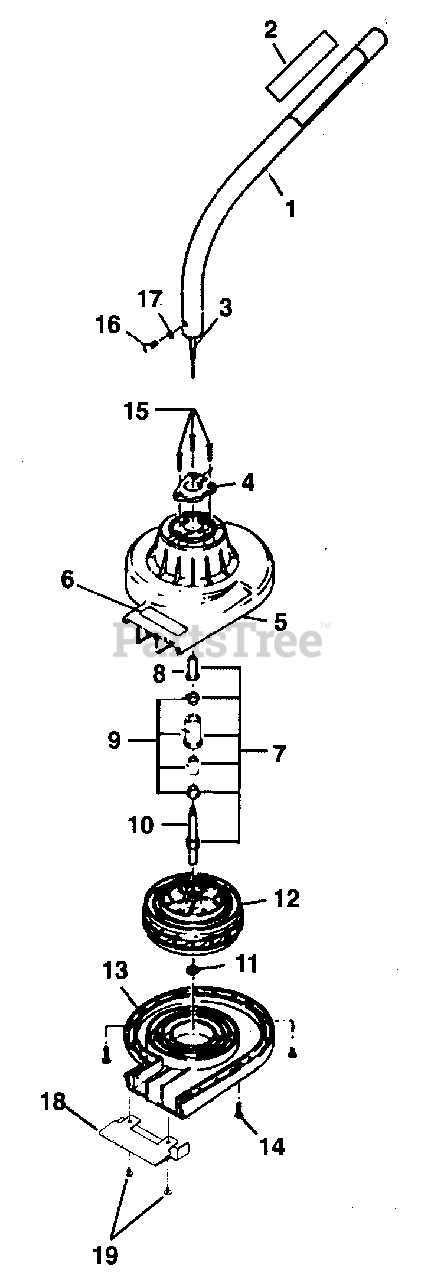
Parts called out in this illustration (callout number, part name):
1	TUBE ASSY
2	LABEL, WARNING
3	FLEX CABLE
5	UPPER HOUSING
6	LABEL, MODEL
7	ARBOR ASSY.
8	ARBOR ADAPTER
9	ARBOR BUSHING ASSY.
10	ARBOR SHAFT
11	SNAP RING
13	LOWER HOUSING
14	SCREW
15	SCREW
16	SCREW
17	LOCK WASHER
18	GUARD, LOWER HOUSING
19	SCREW
